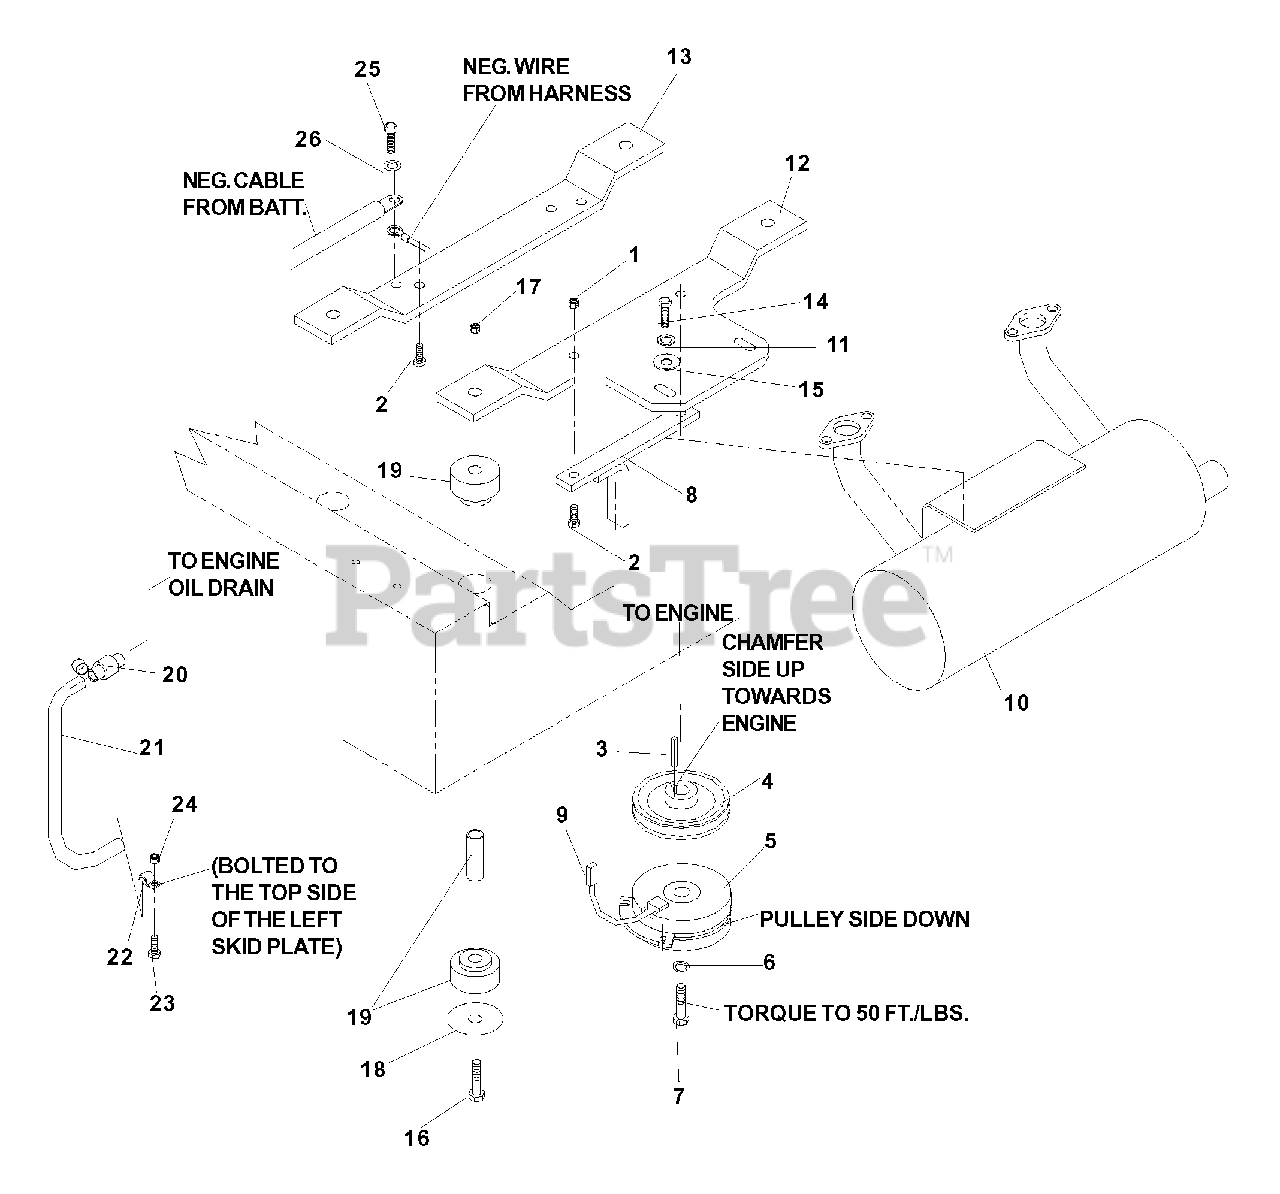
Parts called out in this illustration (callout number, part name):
1	NUT, 5/16C, LOCK
2	HCS, 5/16C x 1 3/4, SERR.
6	LOCKWASHER, 7/16
7	HCS, 7/16F x 2 1/2
8	CLUTCH TIE DOWN
9	KOHLER PIGTAIL
11	LOCKWASHER, 5/16
12	ENGINE MOUNTS
13	ENGINE MOUNTS
14	HCS, 5/16C x 3/4
15	WASHER, 5/16
16	HCS, 1/2C x 3 1/4
17	NUT, 1/2C, NYLOC
18	ISOLATOR WASHER
20	OIL DRAIN FITTING
21	OIL DRAIN HOSE
23	HCS, 1/4C x 3/4
24	NUT, 1/4C, CENTERLOCK
25	SCREW, 3/8 -16, TAP
26	WASHER, EXTERNAL TOOTH
